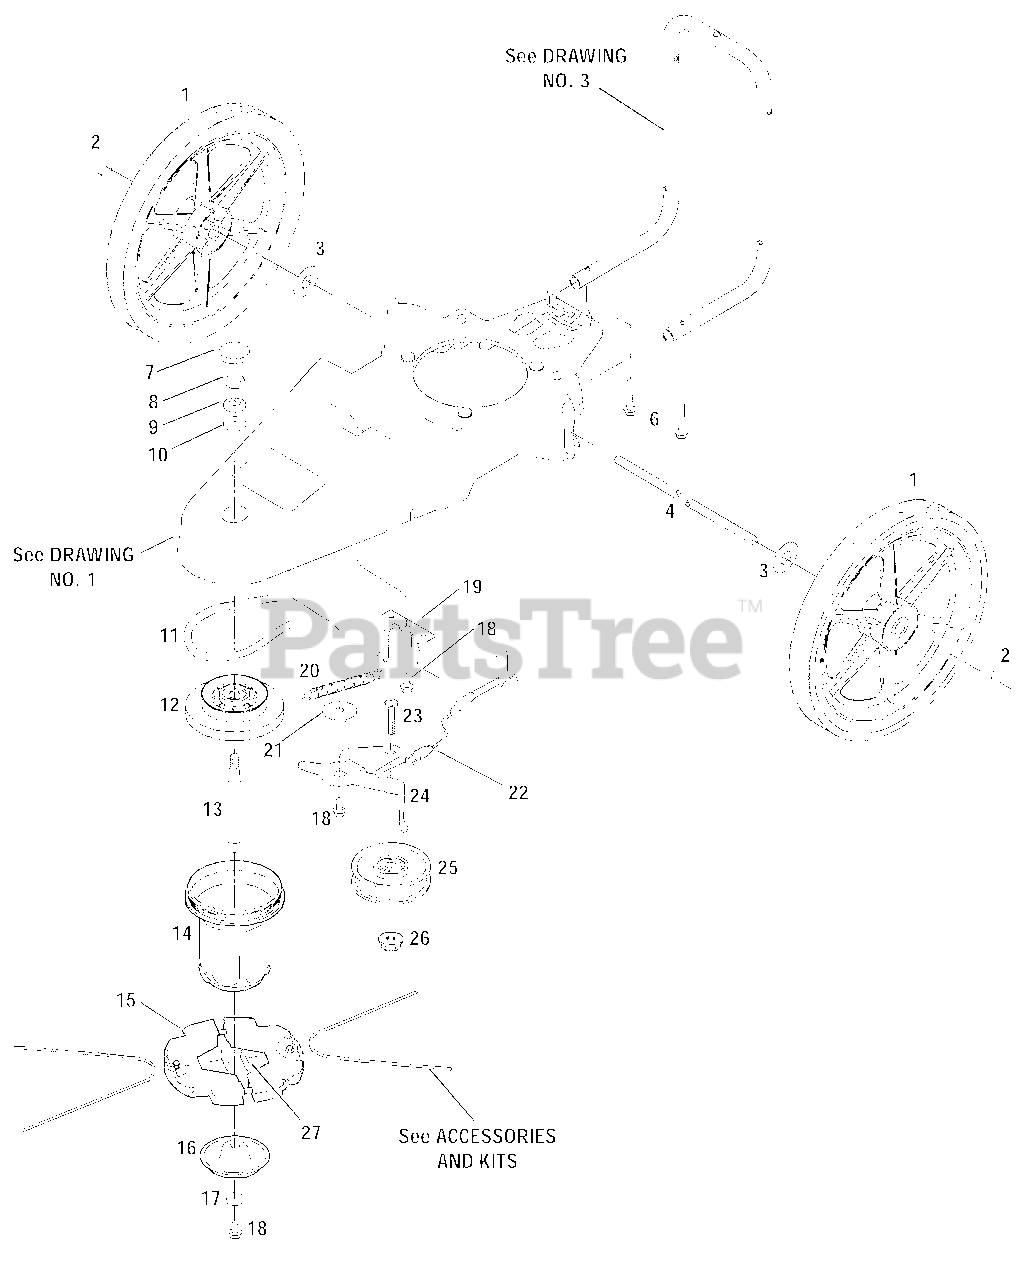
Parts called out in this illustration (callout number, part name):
1	Wheel/Tire Assembly
2	Locking Retaining Ring
3	Flat Washer
6	Self-Tap Screw, 5/16-18 x 2
7	Cap Plug
8	Hex Lock Nut, 1/2-13
9	Belleville Washer
10	Hardened Washer
11	V-Belt 52.88 Lg x .500
12	Spindle Head Adapter
13	Spindle Shaft
14	Spindle Head Assembly
15	Trimmer Head Assembly
16	Wear Cup
17	Square Washer
18	Self-Tap Screw, 5/16-18 x 3/4
19	Cable Bracket
20	Idler Spring
21	Flat Washer
22	Control Cable - Trimmer Head
23	Button Hd. Screw, 3/8-16 x 1-1/2
24	Idler Arm
25	Idler Pulley
26	Flange Lock Nut, 3/8-16
27	Rubber Shim Kit
